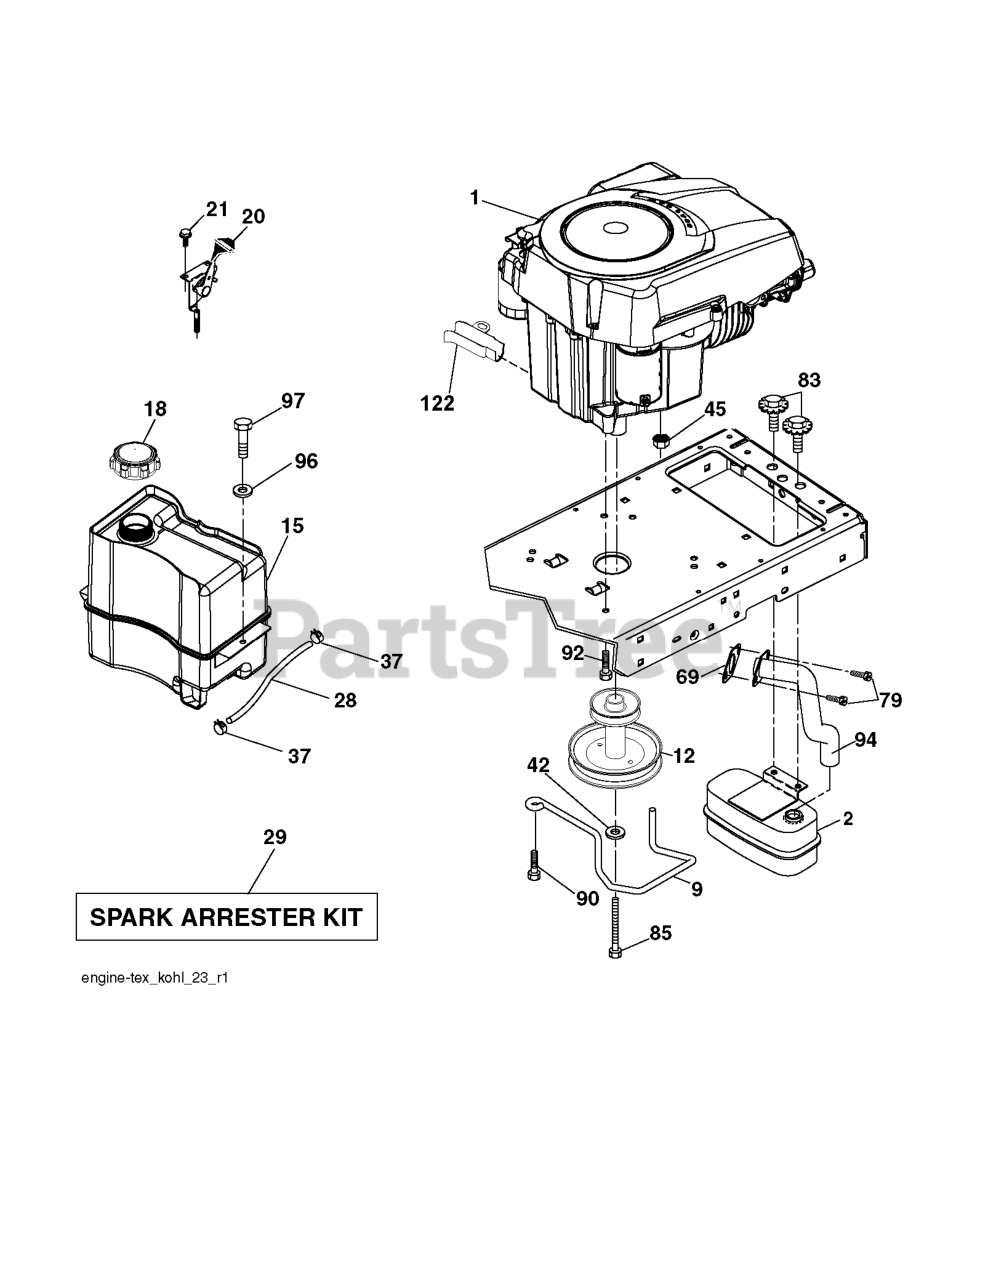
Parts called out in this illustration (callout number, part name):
2	MUFFLER.SINGLE.CYL.KOHL/B&S
9	KEEPER.BELT.ENGINE.3.25 (3 2)
12	PULLEY ENGINE
15	RP TANK FUEL FRT 1.5 GAL
18	CAP ASM.FUEL.2.25"FR.
20	CONTROL.TH/CK.C.
21	SCREW.#10 X 0.750.BOS
28	LINE.FUEL.20
29	KIT.SPARK ARRESTOR 794945 B&S
37	HOSE CLAMP
42	LOCKWASHER
45	NUT
69	GASKET.EXHAUST.KOHLER
79	SCREW.SOCKET HD.5/16-1
83	BOLT.5/16-18UNCX3/4 W/SEMS.BLK
85	BOLT HEX 7/16-20X4-1/4"
90	SCREW 3/8-16X1
92	SCREW 3/8-16X1
94	RP.TUBE.EXHAUST.KOHL.COURAGE
96	WASHER
97	SCREW HEXWSHR 1/4-20X3/4
122	EXTENSION DRAIN OIL
